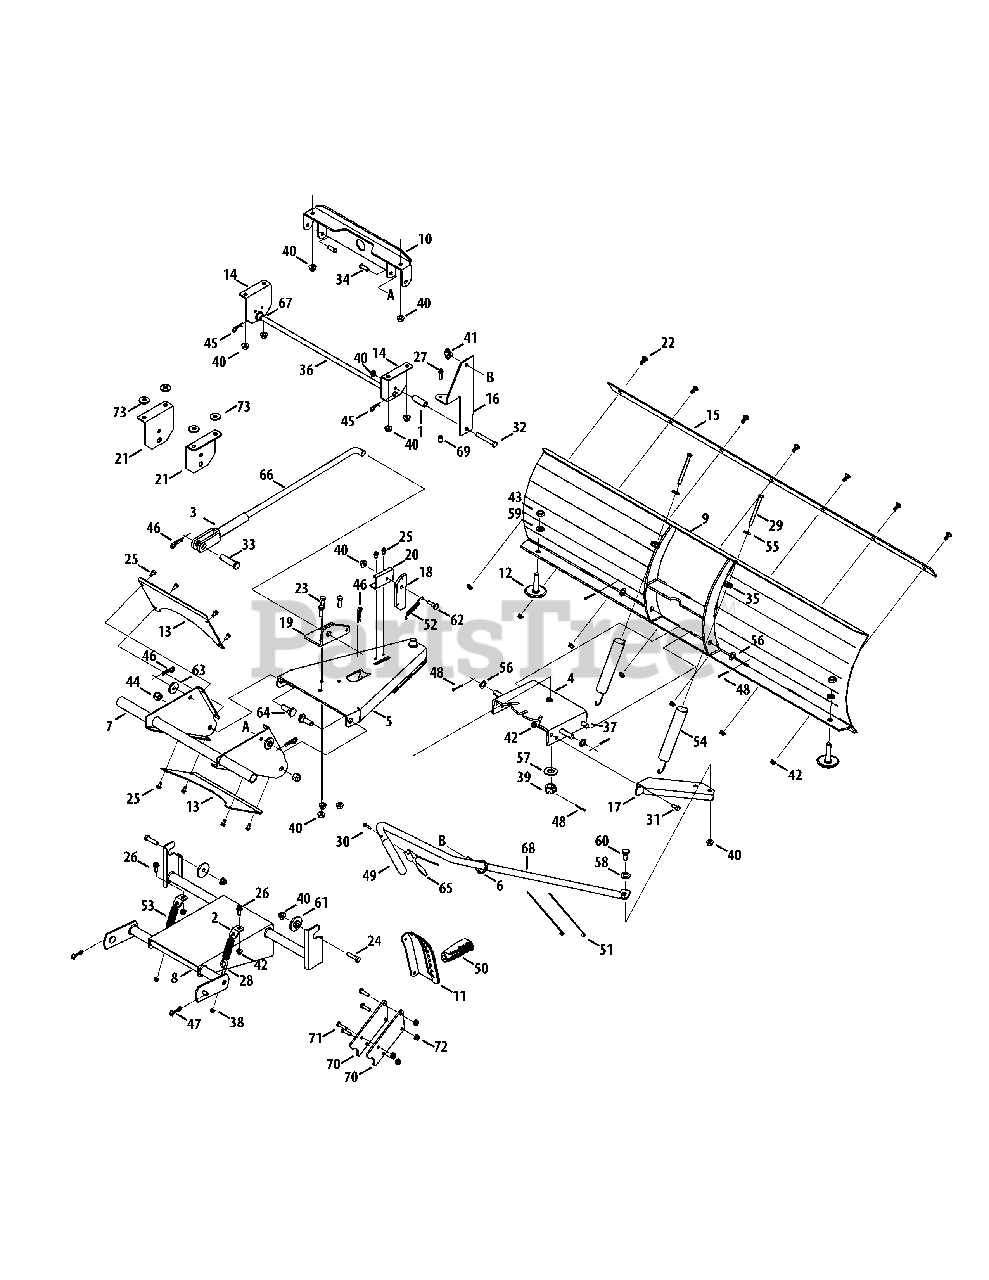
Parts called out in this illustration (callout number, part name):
1	Spacer, .390 x .625 x 1.88
2	Spring Mount Bracket, 45°
3	Clevis Adjustment Assembly
6	Eyebolt Assembly
7	Bracket Assembly
8	Lift Bracket Assembly
9	Blade Assembly. 52"
10	Blade Mount Bracket Assembly
11	Blade Height Adj. Index Bracket
12	Skid Shoe Assembly
14	Mounting Bracket
15	Blade Scraper Plate, 52"
16	Handle Mount Bracket
17	Blade Adjustment Arm
18	Blade Lock Plate
19	Front Lift Bracket
20	Pivot Bracket
22	Carriage Bolt, 5/16-18 x .750
23	Hex Screw, 3/8-16 x 1.00
24	Hex Screw, 3/8-16 x 1.50
25	Hex Washer Screw, 1/4-20 x .500
26	Hex Washer Screw, 5/16-18 x .875
27	Hex Washer Screw, 1/4-20 x 1.000
28	Eye Bolt, 1/4-20
29	Hex Screw, 5/16-18 x 3.50
30	Machine Screw, #10-24 x 1.375
31	SCREW 5/16-18 x .75 GR5
32	Hex Screw, 3/8-16 x 2.75
33	Clevis Pin, .625 x 2.40
34	Clevis Pin, .375 x .969
35	Spring Insert
36	Rod, .50 x 22.65
37	Rod, .50 x 10.428
38	Sems Nut, 1/4-20
39	Slotted Nut, 3/4-16
40	Flange Lock Nut, 3/8-16
41	Wing Nut, 5/16-18
42	HEX FLANGE NUT
43	Jam Nut, 1/2-13
44	Hex Lock Nut, 1/2-13
45	Click Pin, .092 x 1.64
46	Cotter Pin, .125 x 1.75
47	Bow-Tie Cotter Pin
48	Cotter Pin, 1/8 x 1.25
49	Foam Grip
51	Cable Tie, 3/16 x .05 x 7.4
52	Extension Spring, .38 x 3.25
53	Extension Spring, .75 x 3.240
54	Extension Spring, 1.25 x 6.7
55	Flat Washer, .349 x .879 x .063
56	Flat Washer, .530 x .930 x .050
57	Flat Washer, .760 x 1.500 x .120
58	Flat Washer, .570 x 1.120 x .062
59	Flat Washer, 1/2
60	SHOULDER SCREW .498 DIA x .340
61	Shoulder Spacer, .8840 x .190
62	Shoulder Screw, 5/16-18 x .405 x .435
63	Shoulder Spacer, 1.375 x .380 x .183
64	Shoulder Screw, 1/2-13 x .625 x .36
65	Blade Release Cable
67	Flange Bearing, .503 x .75
68	Blade Adjustment Handle
69	Spacer, .258 x .50 x .50
71	SCREW 1/4-20 X1.00 GR5
72	Flange Lock Nut, 1/4-20
73	Flat Washer, .385 x 1.000 x .135
